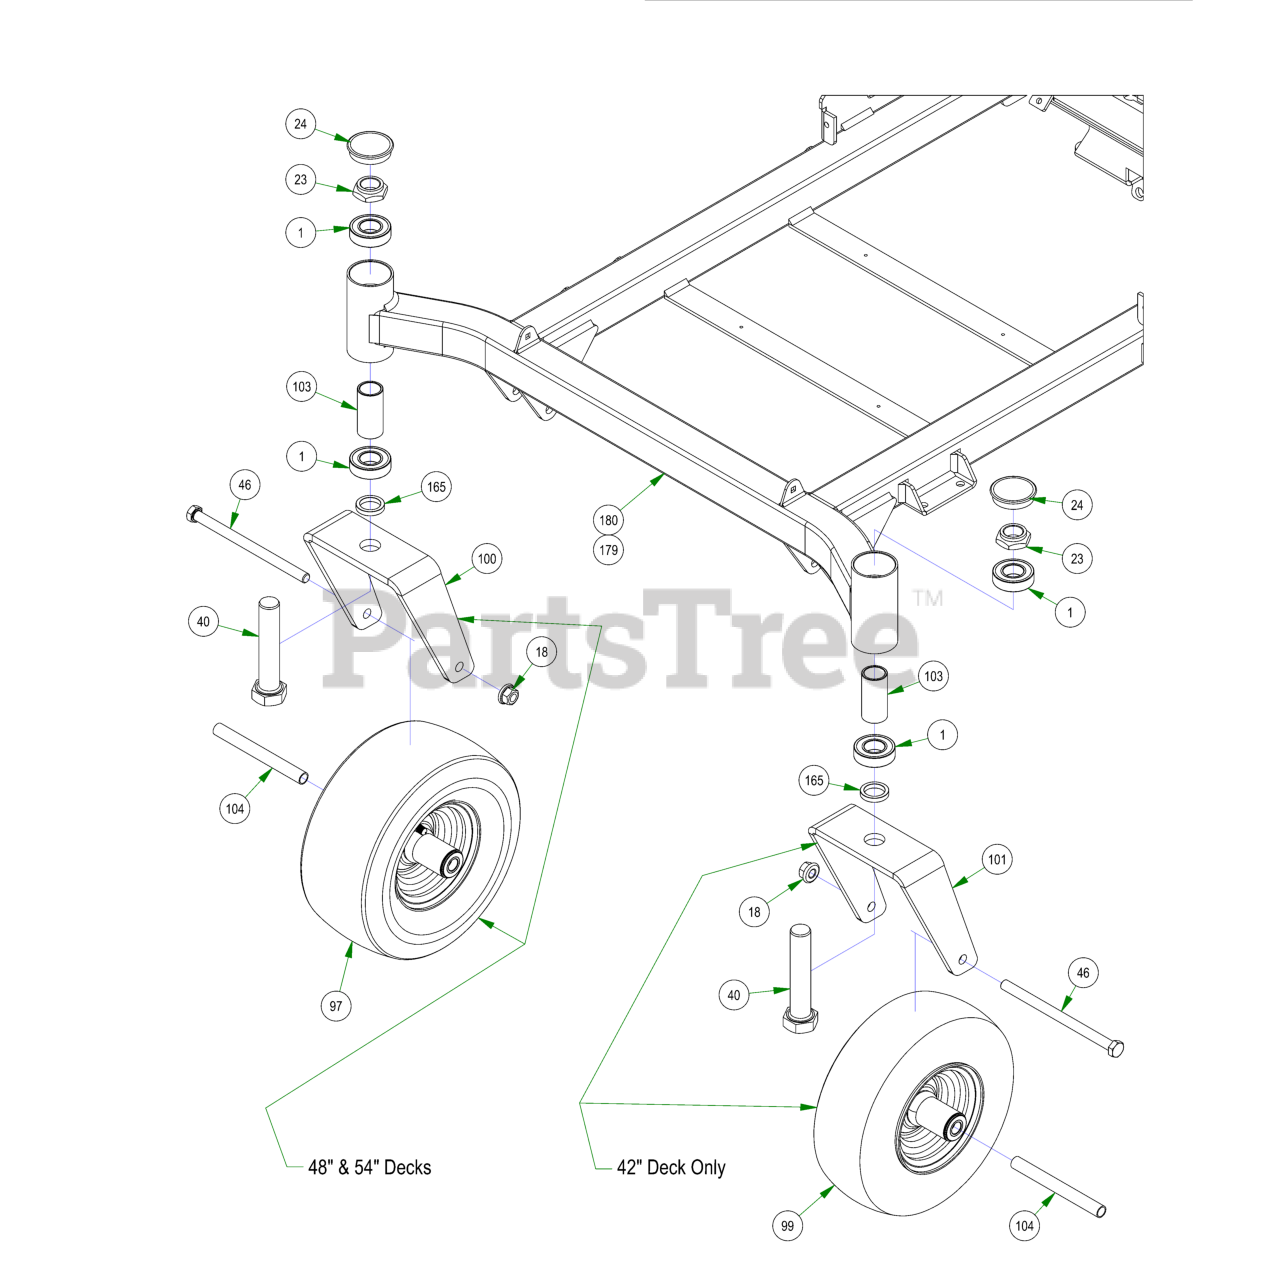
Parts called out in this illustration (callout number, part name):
1	1641 BEARING W/2 CONTACT RUBBER SEALS
18	1/2-13 NYLON INSERT FLANGE LOCKNUT ZINC
23	1"-14 NYLON INSERT JAM LOCKNUT ZINC
24	2017 Bearing Cover
40	1"-14 X 5 HEX CAP SCREW (GR.8) ZINC YELLOW
46	1/2-13 X 7-1/2 HEX CAP SCREW (GR.5) ZINC
97	11x6.00-5 Front Assembly - Black Wheel
99	11 x 4.00 - 5 Front Tire Assembly (Black)
100	2017 MZ Front fork
101	MZ Front Fork (42" ONLY)
103	2016 Front Bearing Spacer
104	Front Wheel Spanner
165	1.02 ID X 1.38 OD X .250 THK SPACER ZINC
179	2022 MZ/ZT 54"-60" Frame
180	2022 MZ/ZT 42"-48" Frame
